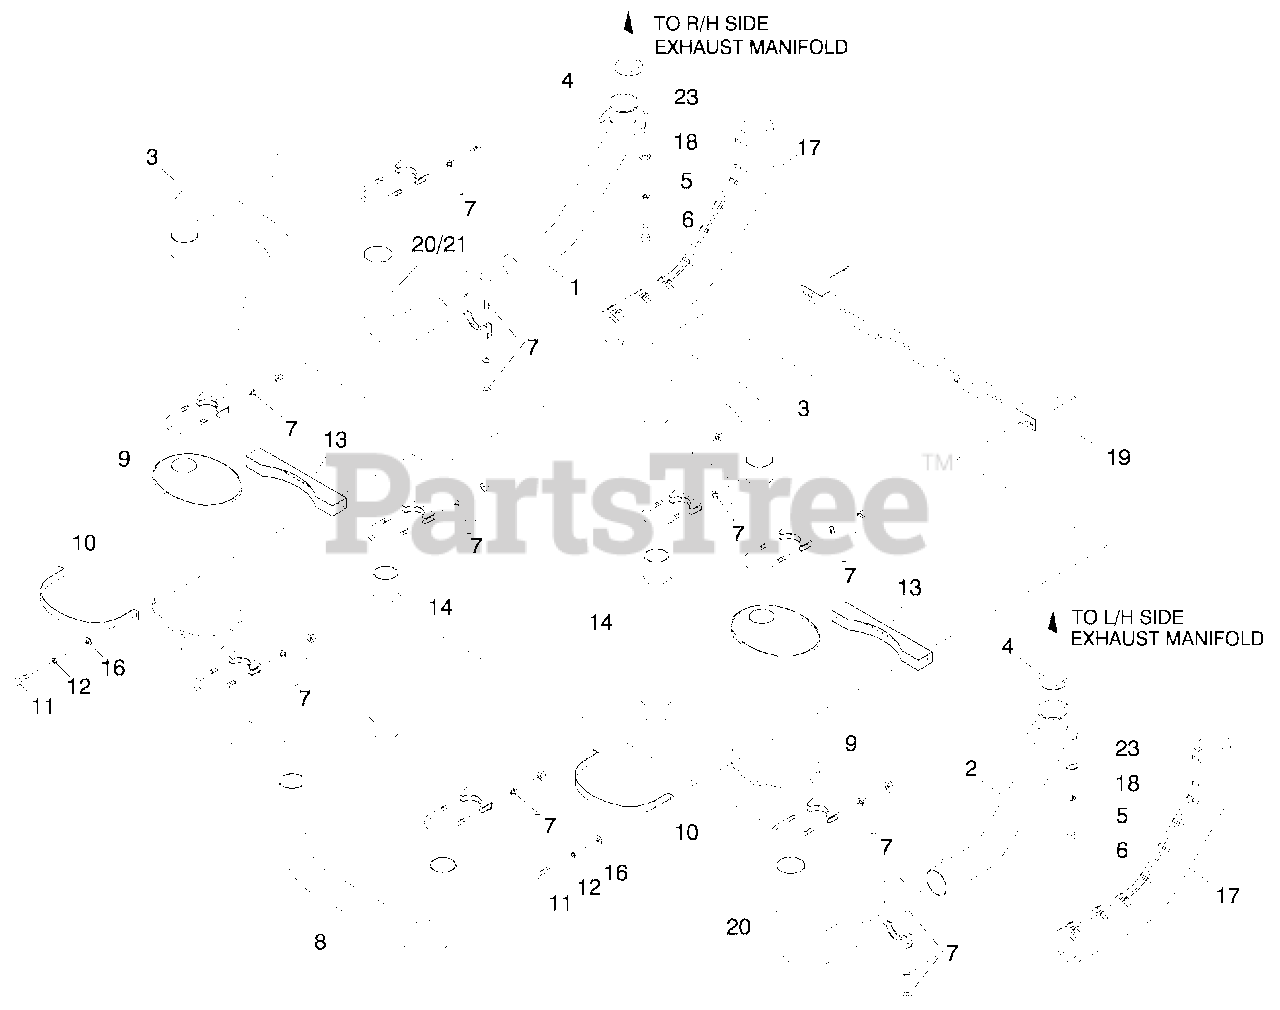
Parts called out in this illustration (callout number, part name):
1	PIPE, EXH MANIFOLD 6.8L C3 RH (6.8L 70KW)
2	PIPE EXH MANIFOLD 6.8L C3 LH (6.8L 70KW)
3	PIPE EXHA UST MUFFLERO UT
4	RING GASKET, 2.5DIA
5	WASHER LOCK M10SS
6	SCREW HHC M10-1.5 X 50 SS FTH
7	BOLT U 3/8-16X2.62
8	PIPE EXHA UST CROSSOVER
9	MFLR 7" X 9" X 25" (2) 2.5" IN/2.5" O UT
10	M U FFLER STRAP
11	SCREW HHC M6-1.0X 16 G8.8
12	WASHER LOCK M6-1/4
13	M U FFLER BRACKET STIFFENER
14	GLASS PACK 23.5" LG 2.5" IN/OUT
16	WASHER FLAT 1/4-M6 ZINC
17	EXHA UST BLANKET 800MM LG (6.8L 70KW)
18	WASHER FLAT 3/8 SS
19	BRKT M UFFLER
20	PIPE LH MUFFLER SIDE
21	PIPE RHM UFFLER SIDE
23	FLANGE, EXHAUST
